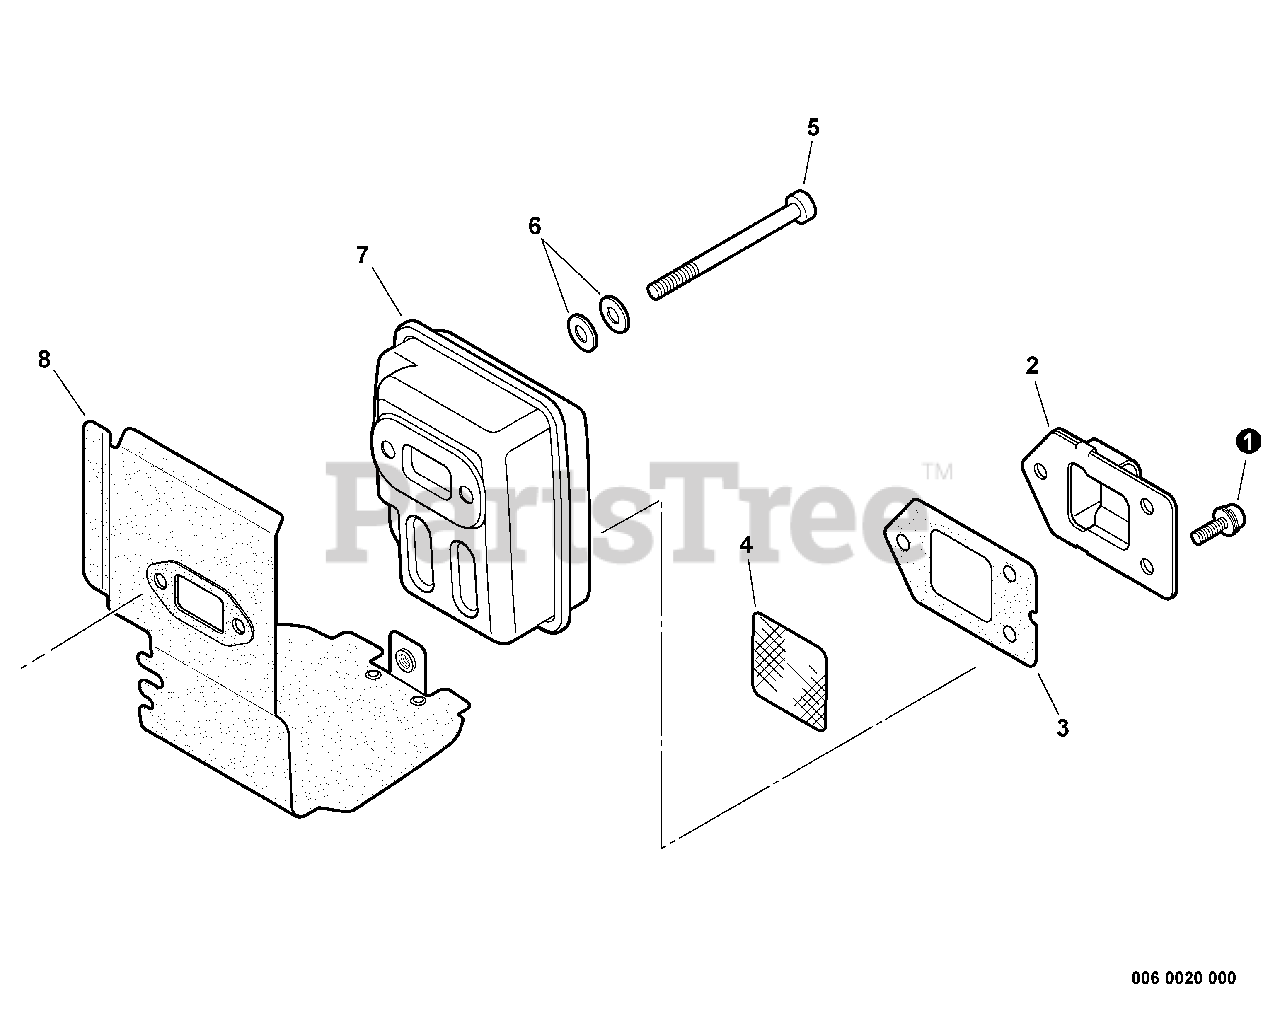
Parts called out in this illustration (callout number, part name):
1	SCREW 4×10
2	GUIDE, EXHAUST
3	GASKET, EXHAUST
4	SCREEN, SPARK ARRESTER
5	BOLT 5×55
6	WASHER, FLAT 5.5×10×0.8
8	HEAT SHIELD, EXHAUST
